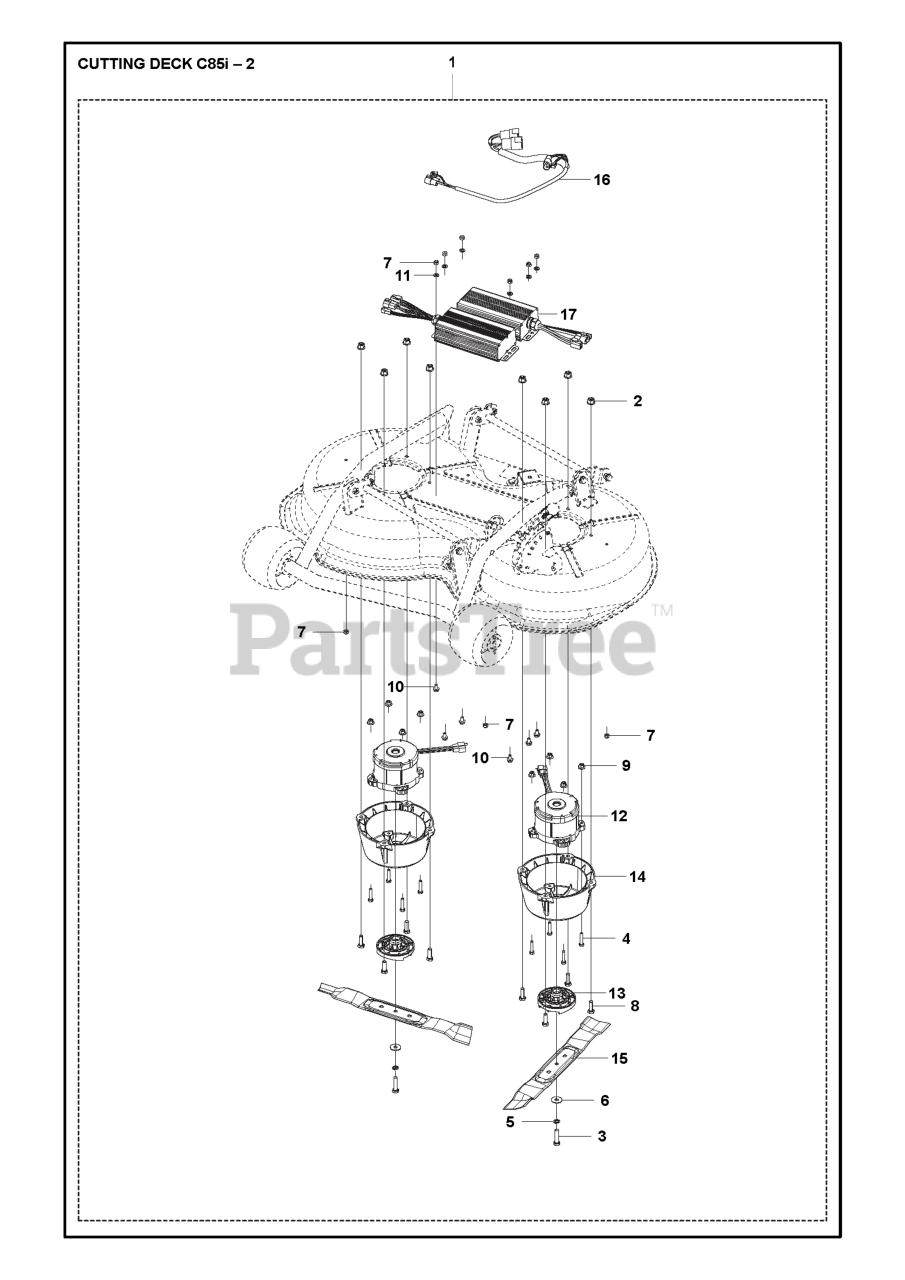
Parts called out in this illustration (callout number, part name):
2	NUT FLANGE
4	SCREW M6S 6X30
5	SPRING WASHER
6	WASHER - 25X8.5X2.3
7	LOCKNUT M6
9	NUT FLANGE
10	SCREW EHHFM
11	WASHER - M6
